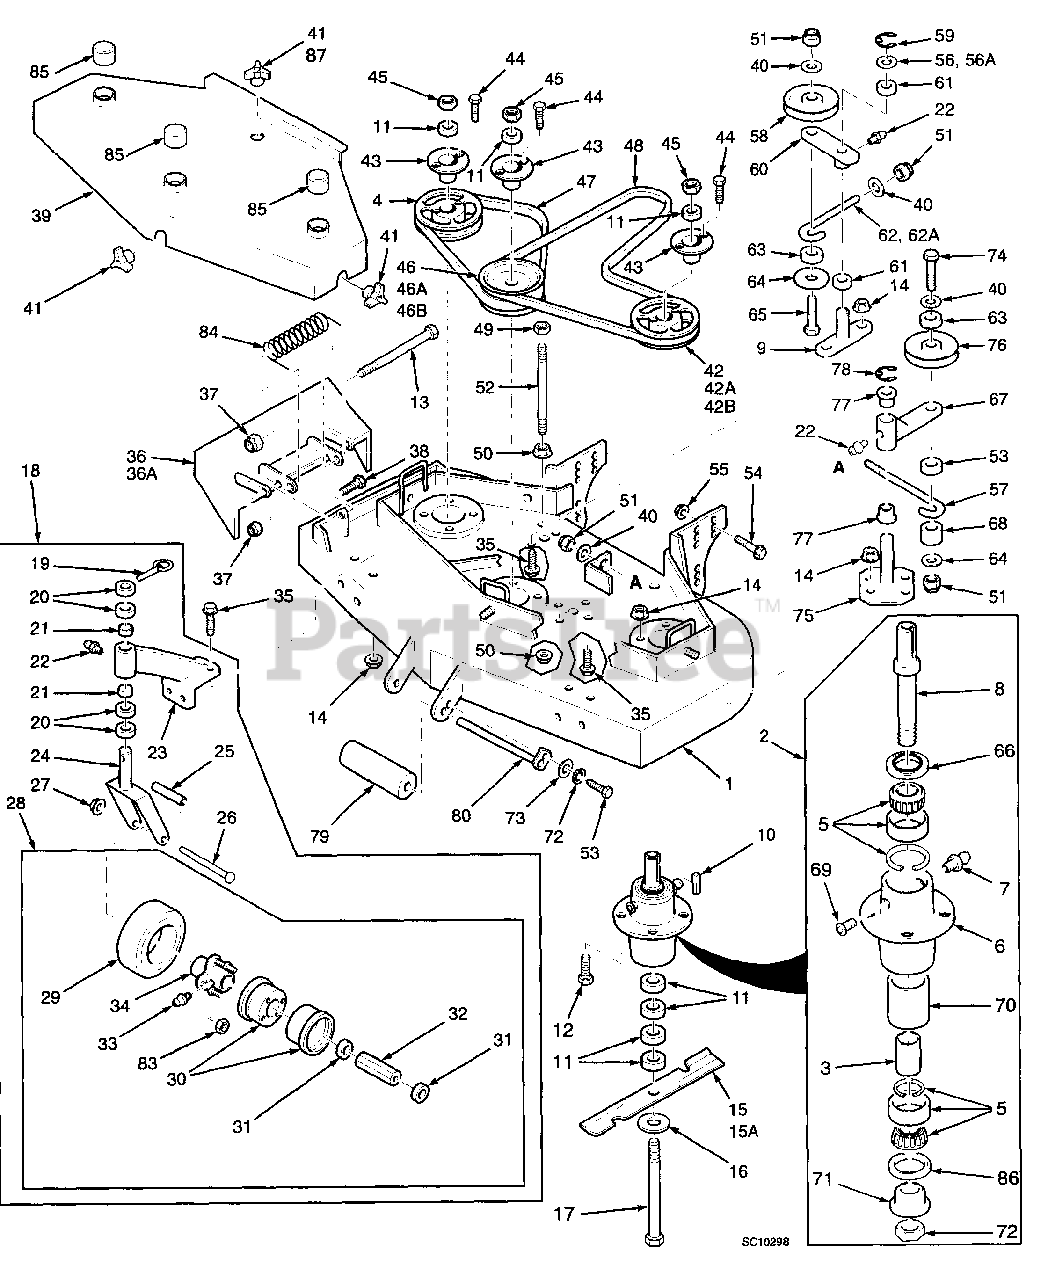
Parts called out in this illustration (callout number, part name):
1	Cutter Deck
2	Spindle Assembly
3	Spacer, Inside
4	Pulley
5	Tapered Bearing (Two)
6	Spindle Housing
7	Grease Fitting Str. 5/16
8	Spindle Shaft, Tapered Brng
9	Idler Pivot
10	Key, 1/4 x 1/4 x 2"
11	Spacer, Cutter Blade - Small
12	Bolt, 5/16-18 x 1-1/4" Hex Head
13	Bolt, 5/16-18 x 4-1/4" Hex Head
14	Serrated Flange Nut, 5/16-18
15	Cutter Blade 24"
16	Flatwasher, 5/8" (.688 x 1.75 x .134)
17	Hex Head Bolt, 5/8-11 x 9-1/2"
18	Caster Assembly,
19	Quick Pin
20	Spacer, Caster Yoke, 1/2" thick
21	Bronze Bearing
22	Lock Wshr, 5/16" (.317 x .586 x .076)
23	Support Assembly,
24	Caster Yoke
25	Sleeve, Caster Wheel Bearing
26	Hex Hd Bolt, 1/2-13 x 5-1/2"
27	Elastic Stop Nut, 1/2-13
28	Wheel Assy.
29	Tire only, Caster Wheel
30	Rim Pair, Caster Wheel
31	Bearing Retainer, Caster Wheel
32	Roller Bearing, Caster Wheel
33	Grease Fitting 45°, 1/4-28
34	Hub Assembly,
35	Capscrew, 5/16-18 x 3/4"
36	Discharge Chute
36A	Discharge Chute
37	Nut, 5/16-18 Elastic Elastic Stop
38	Bolt, 5/16-18 x 1" Hex Head
39	Belt Cover
40	Flat Washer, 3/8"
41	Wing Nut, 3/8-16
42	Pulley
42A	Pulley
42B	Pulley
43	Tapered Hub
44	Bolt, 1/4-20 x 3/4" Hex Head
45	Nut, 5/8-11 Hex
46	Pulley, Double
46A	Pulley, Double
46B	Pulley, Double
47	Belt, RH Blade Drive
48	Belt, Blade Drive
49	Nut, 3/8-16, Nut Centerlock
50	Nut, 3/8-16, Serrated Flange
51	Nut, 3/8-16 Elastic Stop
52	Support, Belt Cover
53	Bolt, 5/16-18 x 1/2" Hex Head
54	Cpscrw,7/16-14 x 1" Ser Flng H Hd
55	Nut, 7/16-14 Serrated Flange
56	Flat Washer 3/4"
56A	Flat Washer 3/4"
57	J-Hook
58	Idler Pulley, "V" Groove
59	Retaining Ring, 3/4" Ext. "E"
60	Idler Arm Assy.
61	Bronze Bearing
62	J-Rod, Idler Pulley
62A	J-Rod, Idler Pulley
63	Spacer, J-Rod
64	Washer, 3/8 x 1-1/2 x 16 ga.
65	Bolt, 3/8-16 x 2-1/4" Hex Head
66	Seal, Cutter Spindle
67	Idler Arm Assy.
68	Spacer, J-Rod
69	Relief Fitting, Cutter Spindle
70	Spacer, Outside, Cutter Spindle
71	Spindle Bushing
72	Nut, Cutter Spindle
73	Flat Wash., 5/16" (.375 x .875 x .083)
74	Bolt, 3/8-16 x 3-1/2" Hex Head
75	Idler Pivot
76	Idler Pulley, Belt Clutch
77	Bronze Bearing
78	Retaining Ring
79	Guide Roller
80	Roller Shaft
83	Nut, 3/8-24 Tapered
84	Spring, Chute Return
85	Spindle Shield
86	Seal, Cutter Spindle
87	Wingnut, 3/8 (Small) 48" Only
